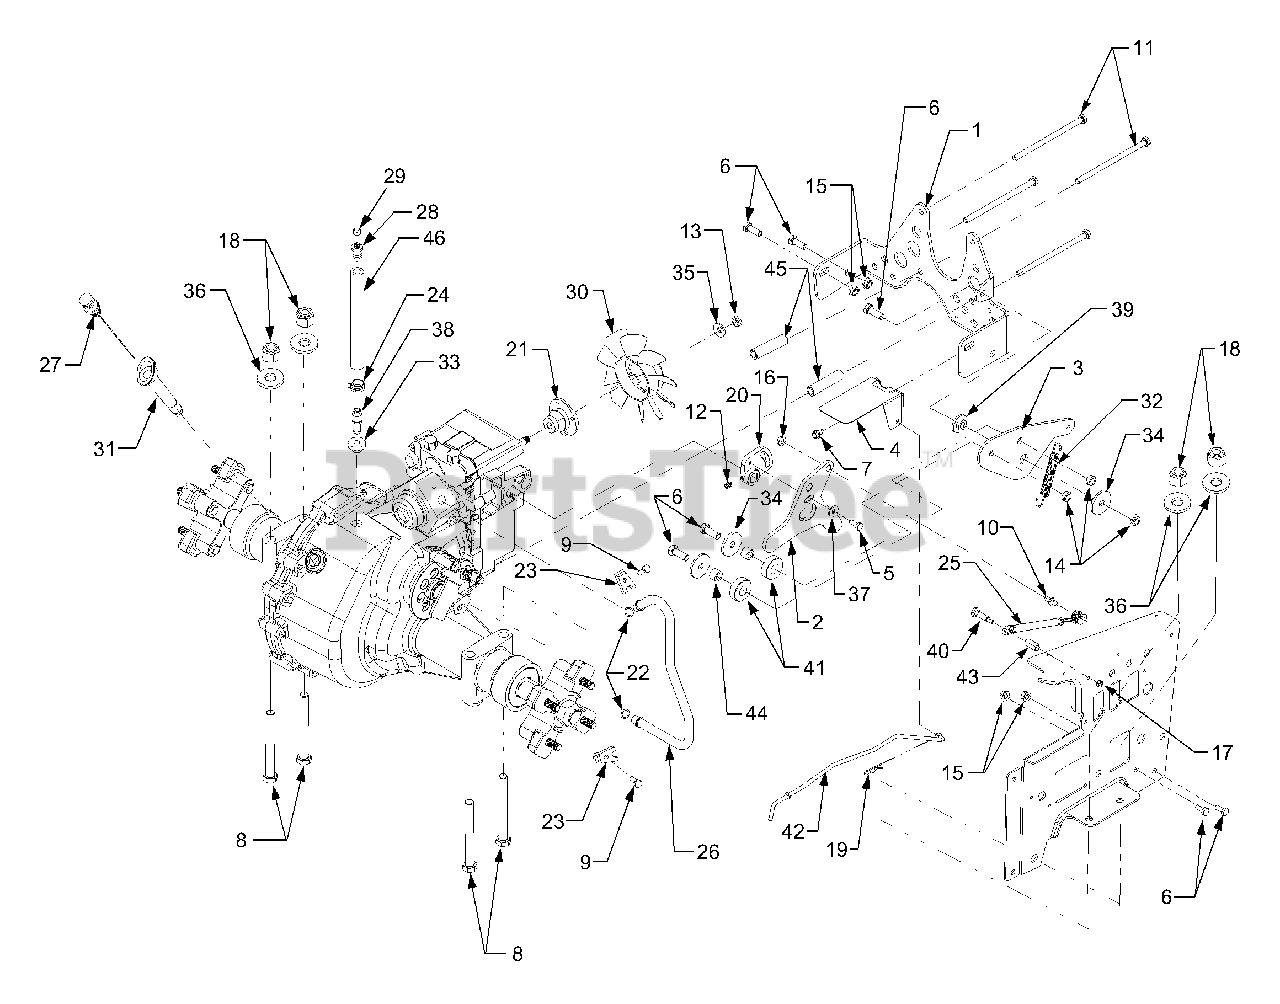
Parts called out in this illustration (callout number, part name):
1	Bracket, Torque
2	Plate, Hydro Neutral Return
3	Link, Neutral Return Bearing
5	Screw, Hex Cap, 1/4-20 x .625 GR5 Lock
6	Screw, Hex Cap, 3/8-16 x 1.0 GR5
7	Screw, Hex Wash. Hd. Tapp, 1/4-20 x .5
8	Screw, Hex Cap, 1/2-20 x 4.5 GR5
9	Screw, Hex Cap, 1/4-20 x .75 GR5
10	Ball Screw, 5/16-18 x .56
11	Screw, Hex Wash. Hd. Tapp, 5/16-18 x 5.5 GR5
12	Screw, Set, 5/16 x .5
13	Nut, Hex Top Lock Jam, 1/2-20
14	Nut, Hex Ctr. Lock Jam, 3/8-16
15	Nut, Hex Flange Lock, 3/8-16
16	Nut, Hex Flange Lock, 5/16-18
17	Nut, Hex, 1/4-20
18	Nut, Hex Insert Lock, 1/2-20
19	Pin, Internal Cotter
20	Arm, Hydro
21	Adapter, Pump
22	O-Ring, .426 ID x .566 OD x .070
23	Clamp, Tube
24	Clamp, Hose
25	Cylinder, Damper
26	Tube, Hydro Pickup
27	Dipstick, Transmission
28	Plastic Vent
30	Fan, Pump
31	Holder, Dipstick
32	Spring, Extension
34	Washer, Flat, .390 x 1.5 x .1
35	Washer, Bell, .5 x 1.0 x .05
36	Washer, Flat, .531 x 1.062 x .134
37	Washer, Flat, .26 x .72 x .06
38	Fitting, Tube
39	Spacer, Shoulder
40	Shoulder Bolt
41	Bearing, Ball
42	Rod, Pump Bypass
43	Spacer, .375 x .5 x 1.02
44	Spacer, .375 x .624 x .445
45	Spacer, Hydro, .3223 x .60 x 2.44
